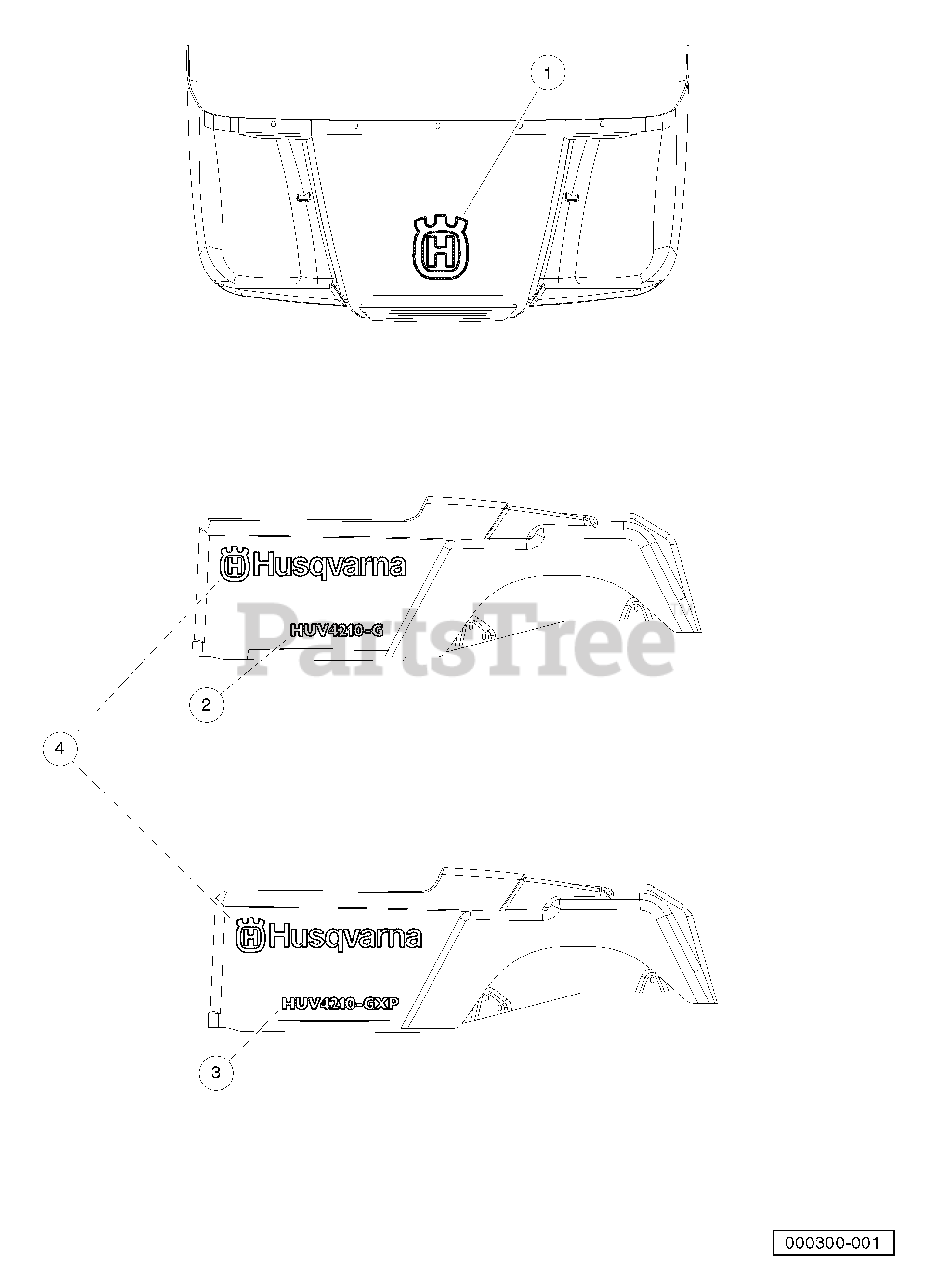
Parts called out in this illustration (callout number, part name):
1	Decal, Husqvarna, Cowl
2	Decal, Husqvarna, Side Panel
3	Decal, Husqvarna, Side Panel
4	Decal, Husq, Side
